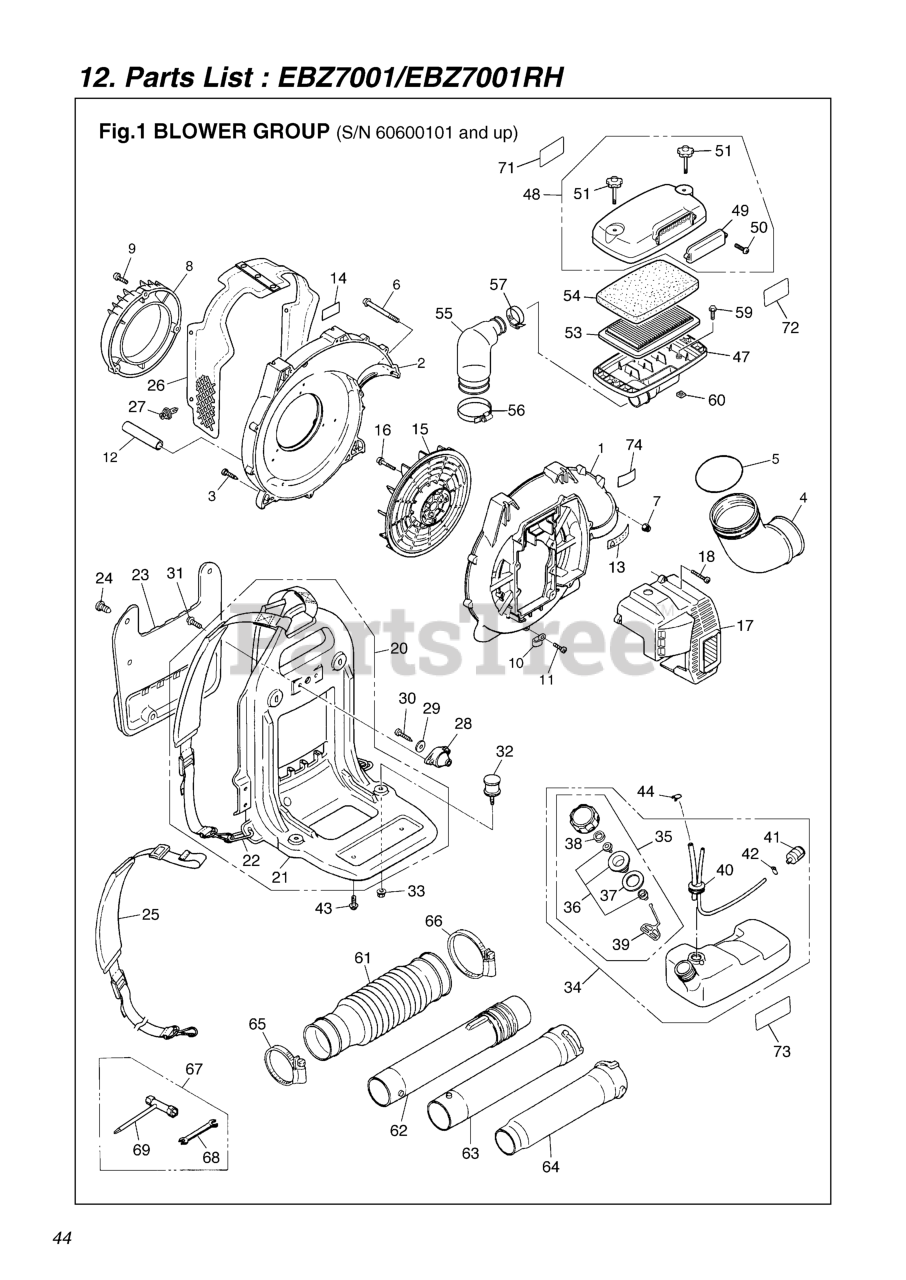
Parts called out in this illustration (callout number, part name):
1	VOLUTE CASE
2	VOLUTE COVER
3	SCREW
4	ELBOW
5	O-RING
6	SCREW TORX
7	NUT (B)
8	COVER, INLET
9	SCREW
10	CLAMP (RPLS 1140-72231)
12	TUBE (RPLS. 07270-01507)
13	LABEL, CAUTION (RPLS -31910)
14	LABEL, NET
15	FAN
16	BOLT
17	ENGINE COVER
18	SCREW
20	FRAME ASSY.
21	FRAME COMP
22	RING (REPLACES -21120)
23	PAD
24	CLIP (RPLS 3490-21320)
25	BAND ASSY (RPLS 2750- )
26	NET COMPLETE
27	CLIP
28	DAMPER, UPPER
30	BOLT, TORX
31	SCREW TORX
32	DAMPER, LOWER
33	NUT, M6
34	TANK ASSY (RPLS. -85100)
35	CAP ASSY (RPLS -85201)
36	HOLDER (REPLACES -85230)
37	PACKING
38	FILTER
39	STOPPER
40	PIPE COMPLETE
41	FILTER ASSY
42	CLIP (REPLACES 2841-31280)
43	SCREW TORX
44	CLIP
47	BODY (RPLS. T4012-82111)
48	COVER ASSY
49	COVER
50	SCREW
51	KNOB BOLT
53	ELEMENT (PAPER)
54	ELEMENT (FOAM) (RPLS -82320)
55	HOSE
56	CLAMP
57	CLAMP
59	BOLT (USE 848-815-2000)
60	NUT
61	FLEX HOSE
62	SWIVEL JOINT
63	PIPE, STRAIGHT
64	PIPE, END
65	CLAMP
66	CLAMP
67	TOOL-SET
68	SPANNER, 8 X 10 (RPLS 2540- )
71	LABEL
72	LABEL, EBZ7001
73	LABEL
74	LABEL, SOUND
